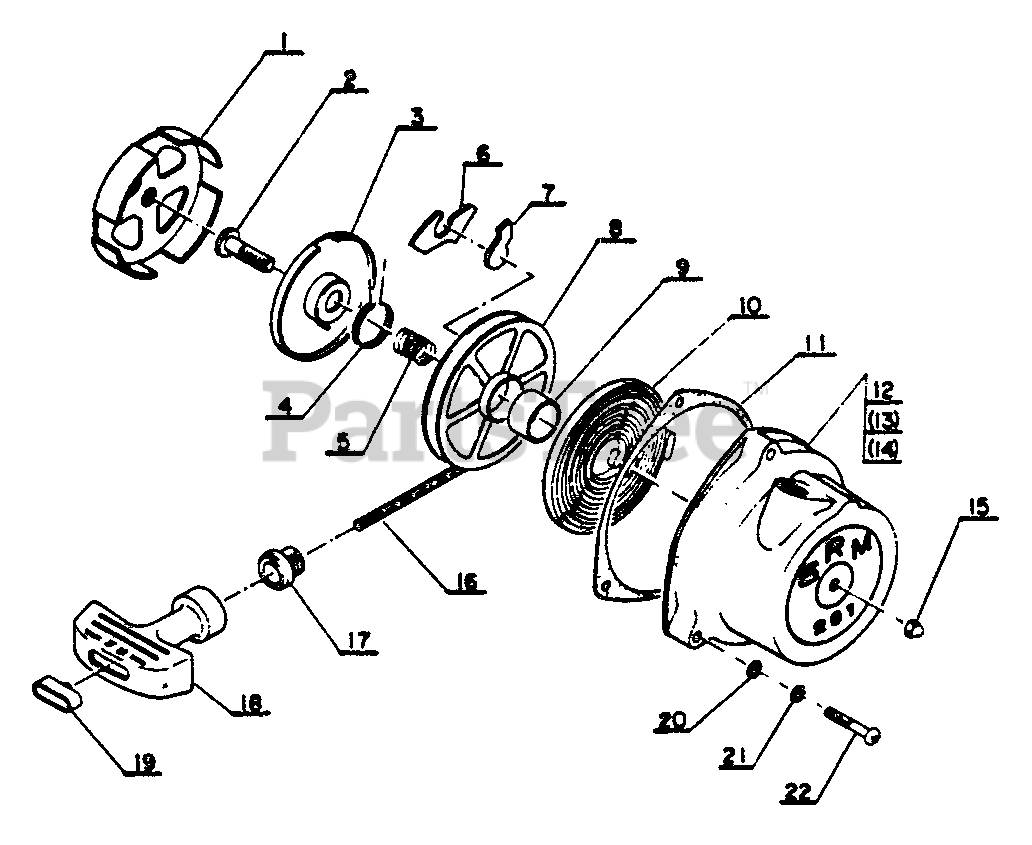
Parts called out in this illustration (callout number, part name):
1	CATCHER, PAWL
2	SCREW - SET
3	RETAINER
4	SPRING, REWIND
6	CAM, RECOIL
7	RATCHET
8	REEL, ROPE
10	SPRING, REWIND
11	CASE, STARTER
12	CASE, STARTER
16	ROPE, STARTER
17	GUIDE, ROPE
18	GRIP, STARTER
19	RETAINER, ROPE
20	WASHER - 4
21	LOCKWASHER - 4
22	SCREW - 4X25
